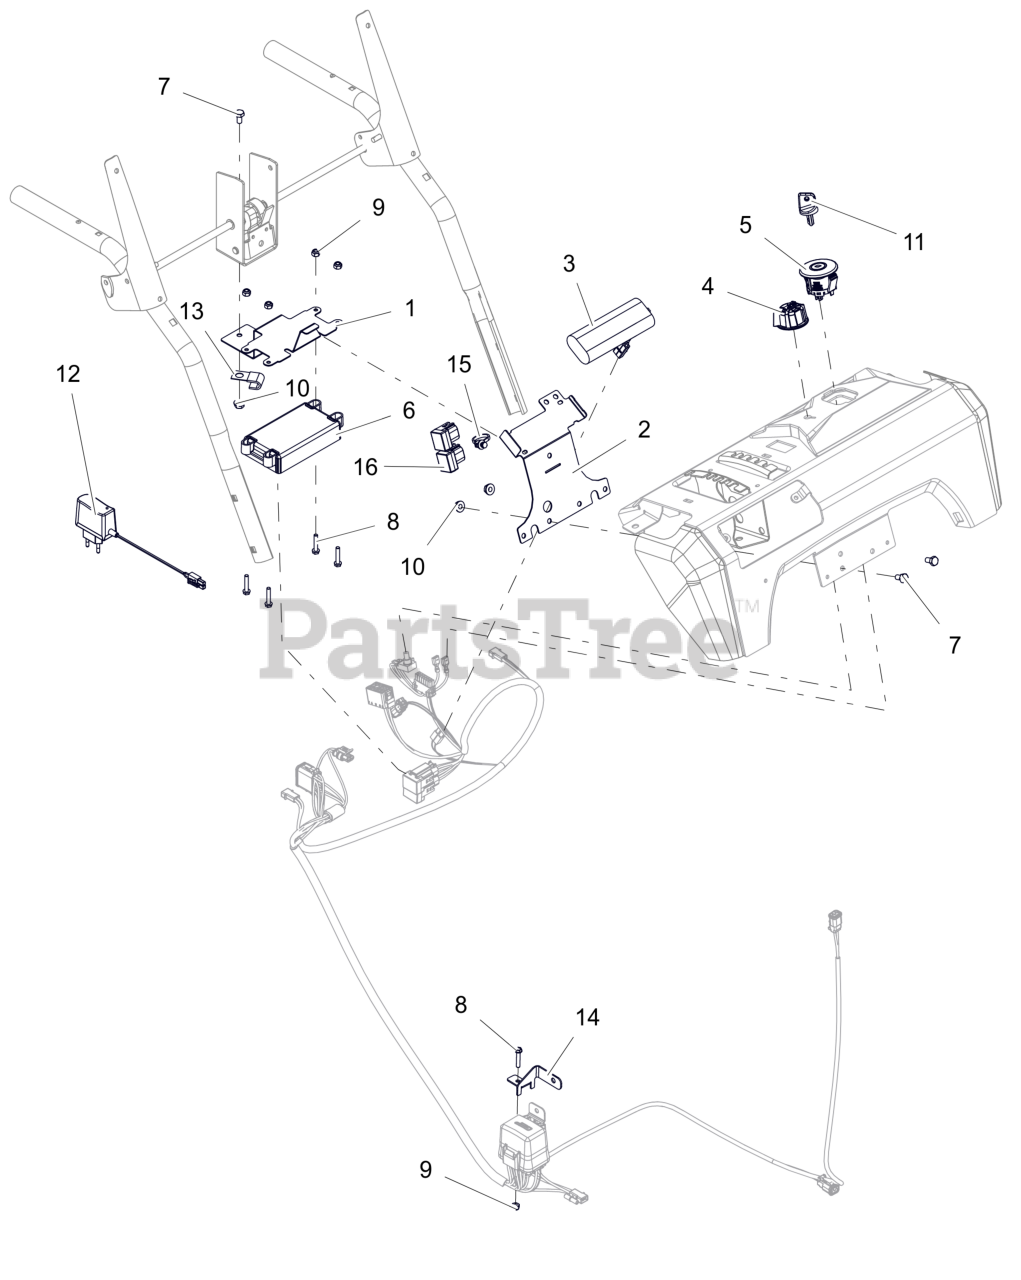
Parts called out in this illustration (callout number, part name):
1	BRACKET, ENGINE EFI-LCT LOWER
2	BRACKET, ENGINE EFI-LCT UPPER
3	BATTERY, SNOW EFI - 7.2V
4	KNOB- CONTROL EFI
5	IGNITION SWITCH ASM - 2 POS
6	ECU SERVICE LCT/CSI - 369CC
7	BLT,HEX .25-20X.50 G5 ZCC
8	BLT, HWH #10-24X1.00 ZCC
9	NUT-LK-NYL #10-24 G2 ZCC
10	NUT-LK-TOP-FLG .250-20 GF ZCC
11	KEY- IGNITION
12	CHARGER, BATTERY-EFI 7.2V (EU)
13	J-CLAMP
14	BRKT, MOUNT RECTIFIER
15	CABLE TIE W/ TREE (.25 HOLE)
16	PACK, DIODE
